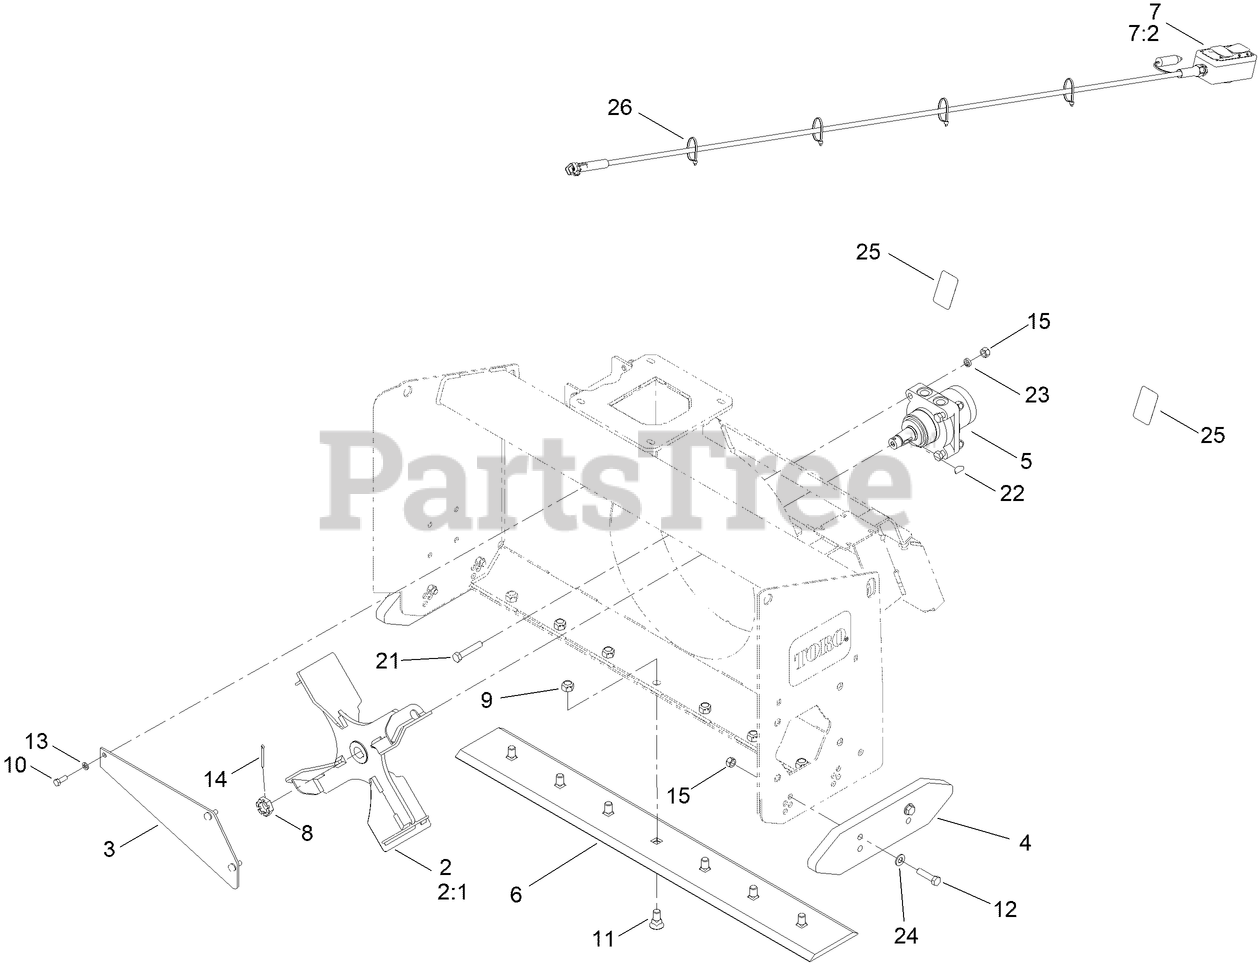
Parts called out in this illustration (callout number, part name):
2	IMPELLER
2:1	KIT-SEAL
3	PLATE-IMPLELLER
4	SHOE-STEEL
4	SHOE-POLY
5	MOTOR-IMPELLER
6	PLATE-LEADING EDGE
7	TORO ELC BOX 2 SWITCH ASM
7:2	DECAL-CHUTE CONTROL
9	NUT-CROWNLOCK
10	SCREW-HH
11	BOLT-PLOW
12	SCREW-HH
13	WASHER-LOCK
14	PIN-COTTER
15	NUT-HEX
21	SCREW-HH
22	KEY-WOODRUFF
23	WASHER - Split Lock, 1/2 x 0.175 Thk
24	WASHER-FLAT
25	KIT-REFLECTOR
26	TIE-CABLE
